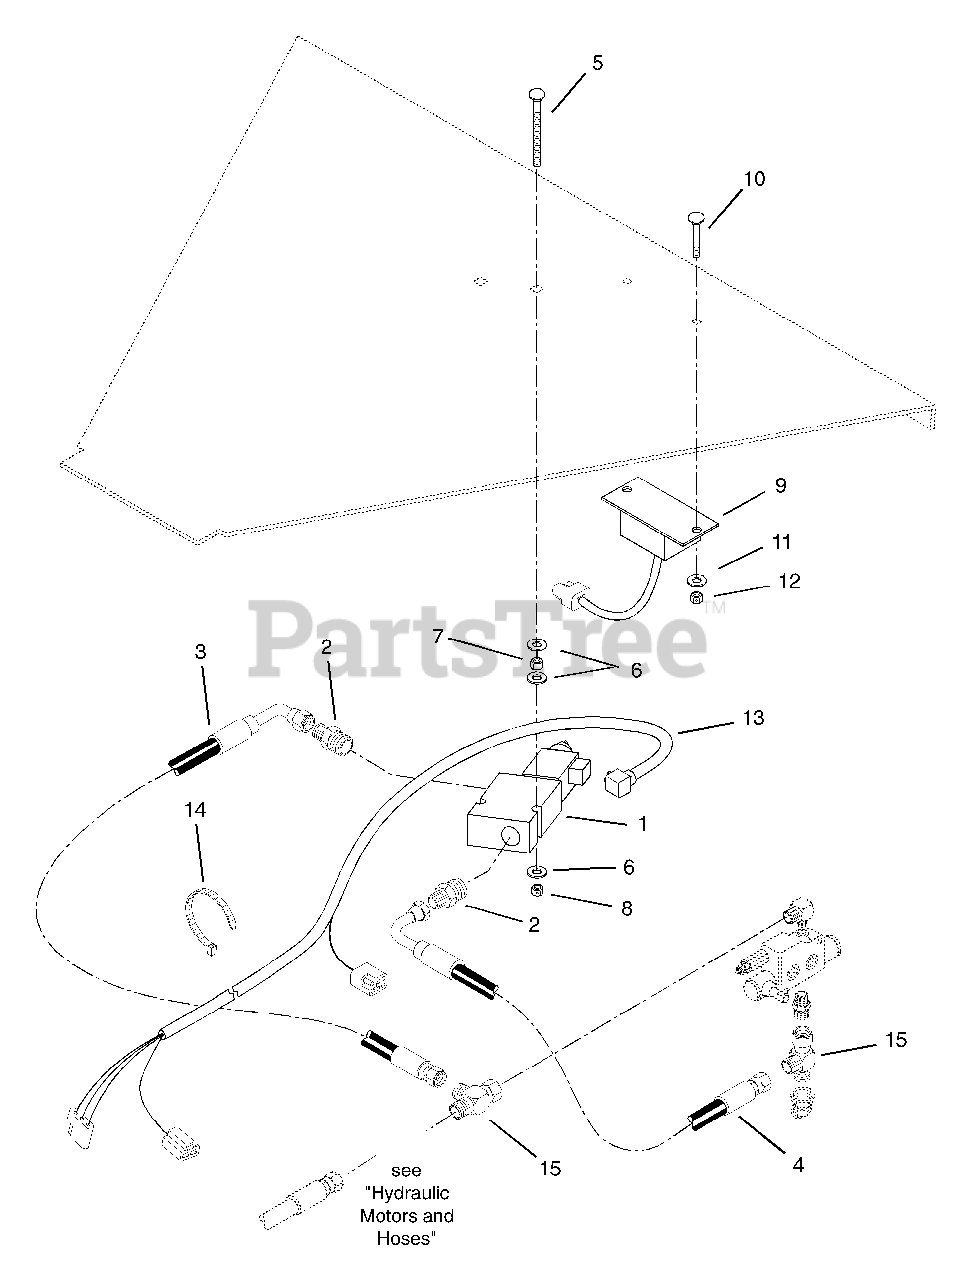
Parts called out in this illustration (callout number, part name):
1	Valve-Autofeed
2	Adapter-Hydraulic Straight 1-1/16 "O" to 3/4
3	Hose-Hydraulic 30" with Elbow
4	Hose-Hydraulic 26.5 inch with Elbow
5	Bolt-Round Head Square Neck .31-18 x 2.75
6	Washer-Flat-Steel .38 x .875 x .083
7	Nut-Hex .31-18
8	Nut-Locking-Center .31-18
9	Module-Autofeed
10	Bolt-Round Head Square Neck .25-20 x 1.00 Grade 5
11	Washer-Flat-Steel .312 x .734 x .065
12	Nut-Locking-Center .25-20
13	Harness-Autofeed Wiring 944
14	Tie Wrap
15	Tee-Swivel
